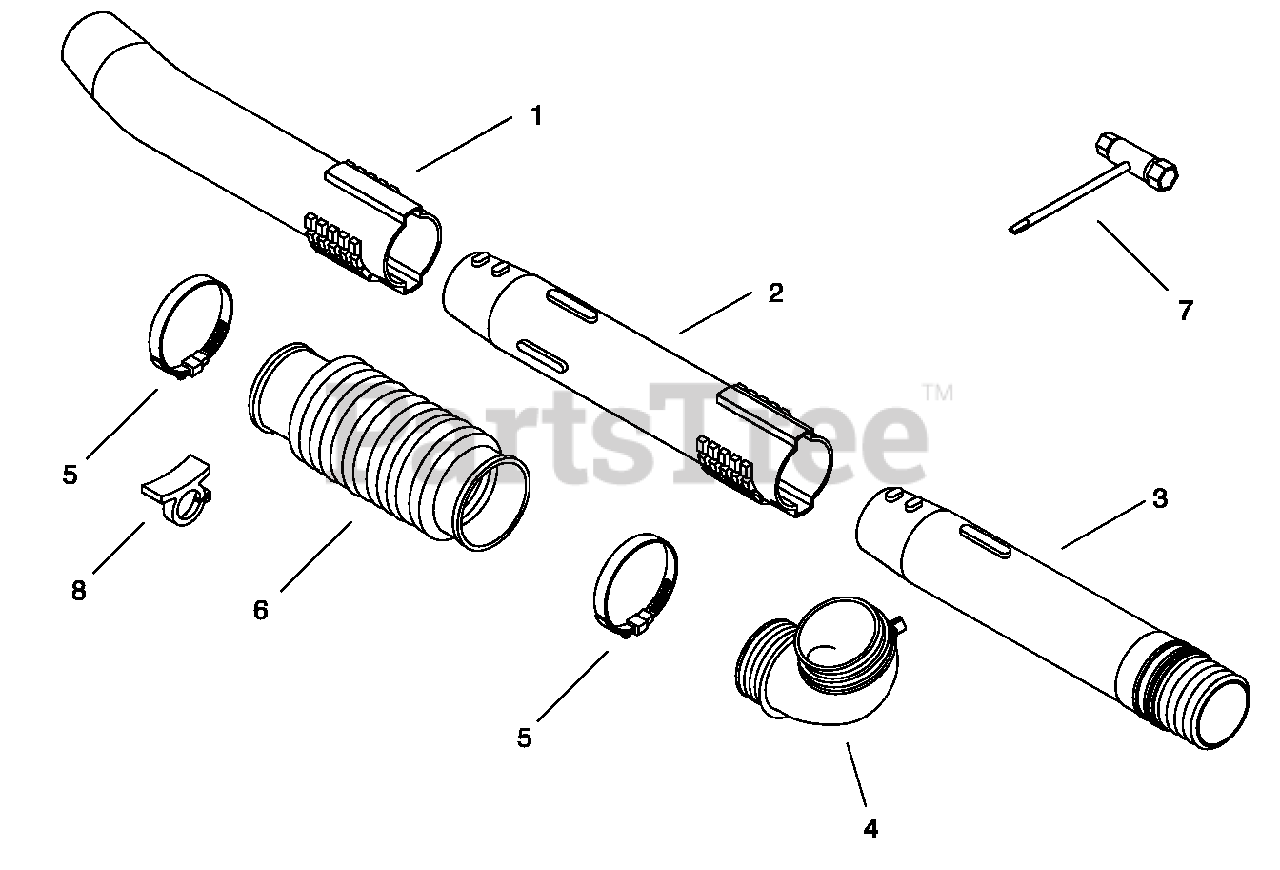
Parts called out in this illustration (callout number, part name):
1	TUBE, BLOWER - ROUND NOZZLE
2	TUBE, BLOWER - STRAIGHT
3	TUBE, BLOWER - SWIVEL
4	TUBE, BLOWER - ELBOW
5	CLAMP 58.7 MM / 82.5 MM
6	TUBE, BLOWER - FLEXIBLE
7	T-WRENCH 10×19 MM
8	CLIP, CABLE
